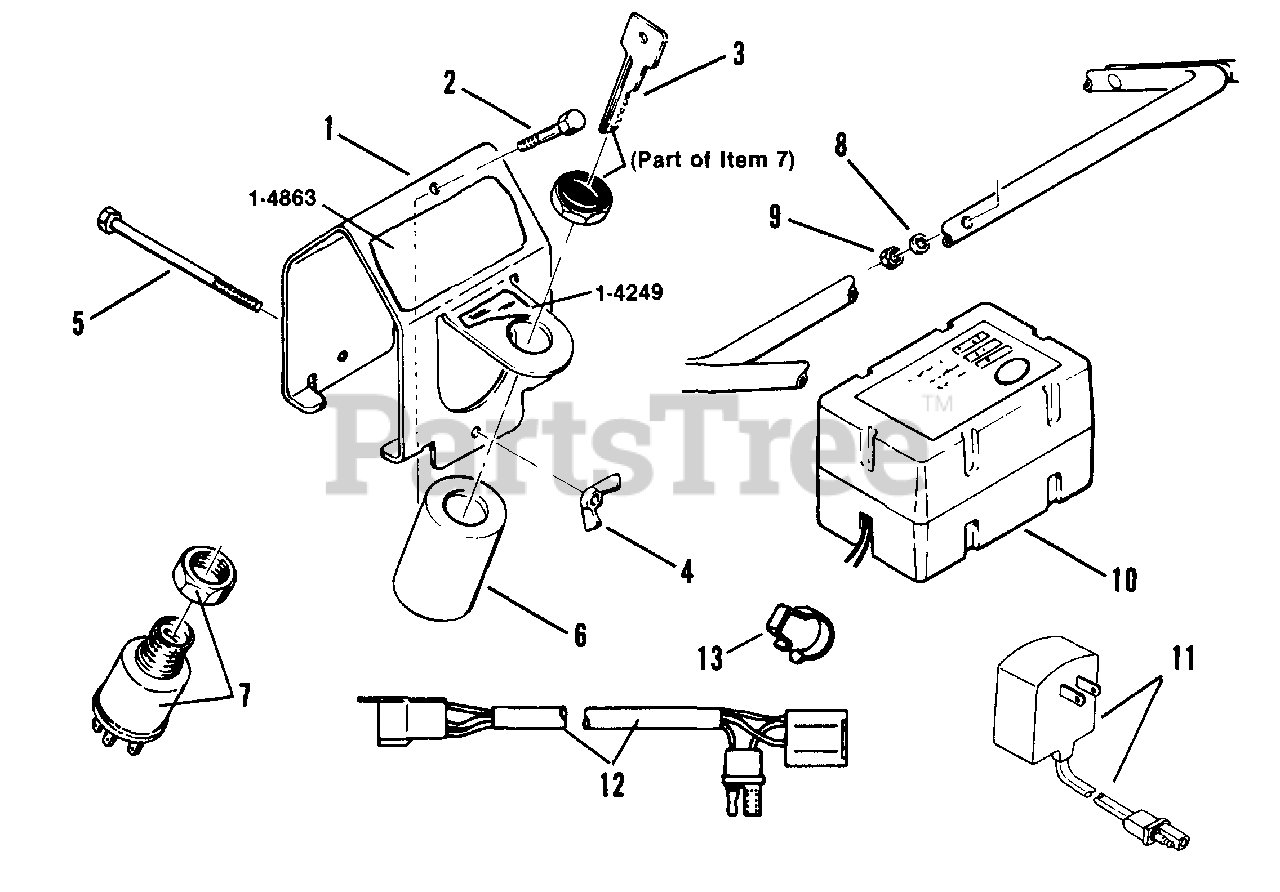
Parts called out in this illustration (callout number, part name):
1	ASSEMBLY, Bracket (7037749)
2	SCREW, 1/4-28 x 1 3/8" Hex Head Cap
3	KEY (Set of 2)
4	NUT, 1/4-28 Wing
5	SCREW, 1/4-28 x 3 1/4" Hex Head Cap
6	COVER, Switch
7	SWITCH, Ignition
8	WASHER, 1/4 Internal Tooth Lock
9	NUT, 1/4-28 Hex
10	BATTERY, 12 Volt, 2.5 AMP
11	CHARGER, Battery (60 Hertz) ('86 & Earlier Models)
12	HARNESS, Wiring (Tec. 52")
13	CLIP, Wiring Harness
